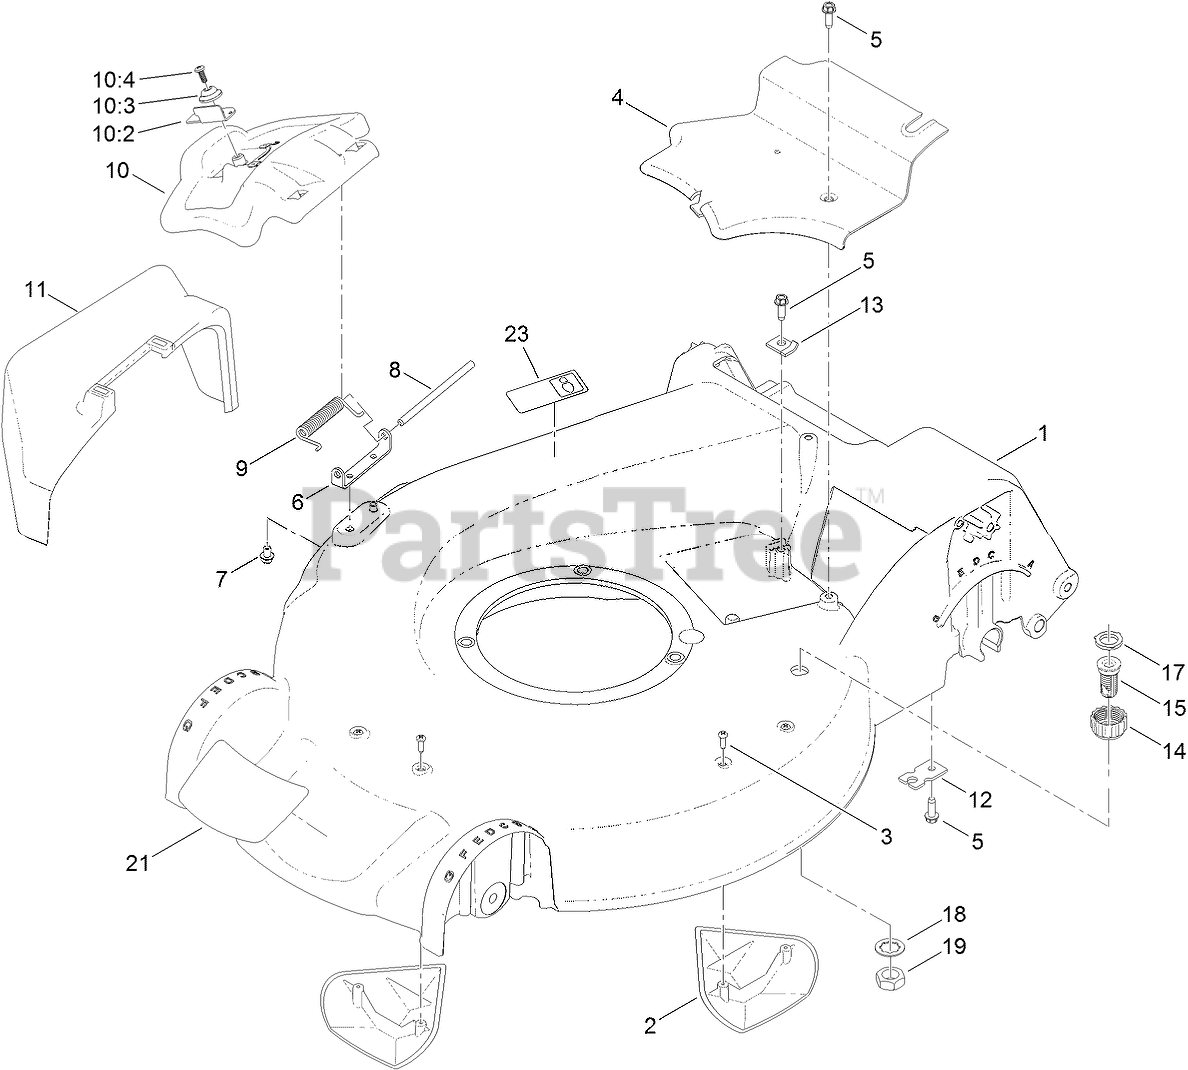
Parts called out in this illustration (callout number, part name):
1	HOUSING ASM
2	KICKER-HOUSING
3	SCREW-PPH
4	COVER-BELT
5	SCREW-HWHTF
6	BRACKET-COVER
7	SCREW-HWH
8	ROD-COVER
9	SPRING-TORSION
10	DISCHARGE DOOR ASM
10:2	LATCH-DOOR
10:3	CAP-DOOR
10:4	SCREW-PLASTITE
11	CHUTE-DISCHARGE, SIDE
12	BRACKET-CABLE, TRACTION
13	CLAMP-CABLE
14	COUPLING-HOSE, WASHOUT PORT
15	PORT-WASHOUT
17	WASHER-SEAL, WASHOUT PORT
18	WASHER-TOOTH, INTERNAL
19	NUT-JAM
21	DECAL-DECK
23	DECAL-PLACEMENT, FOOT
